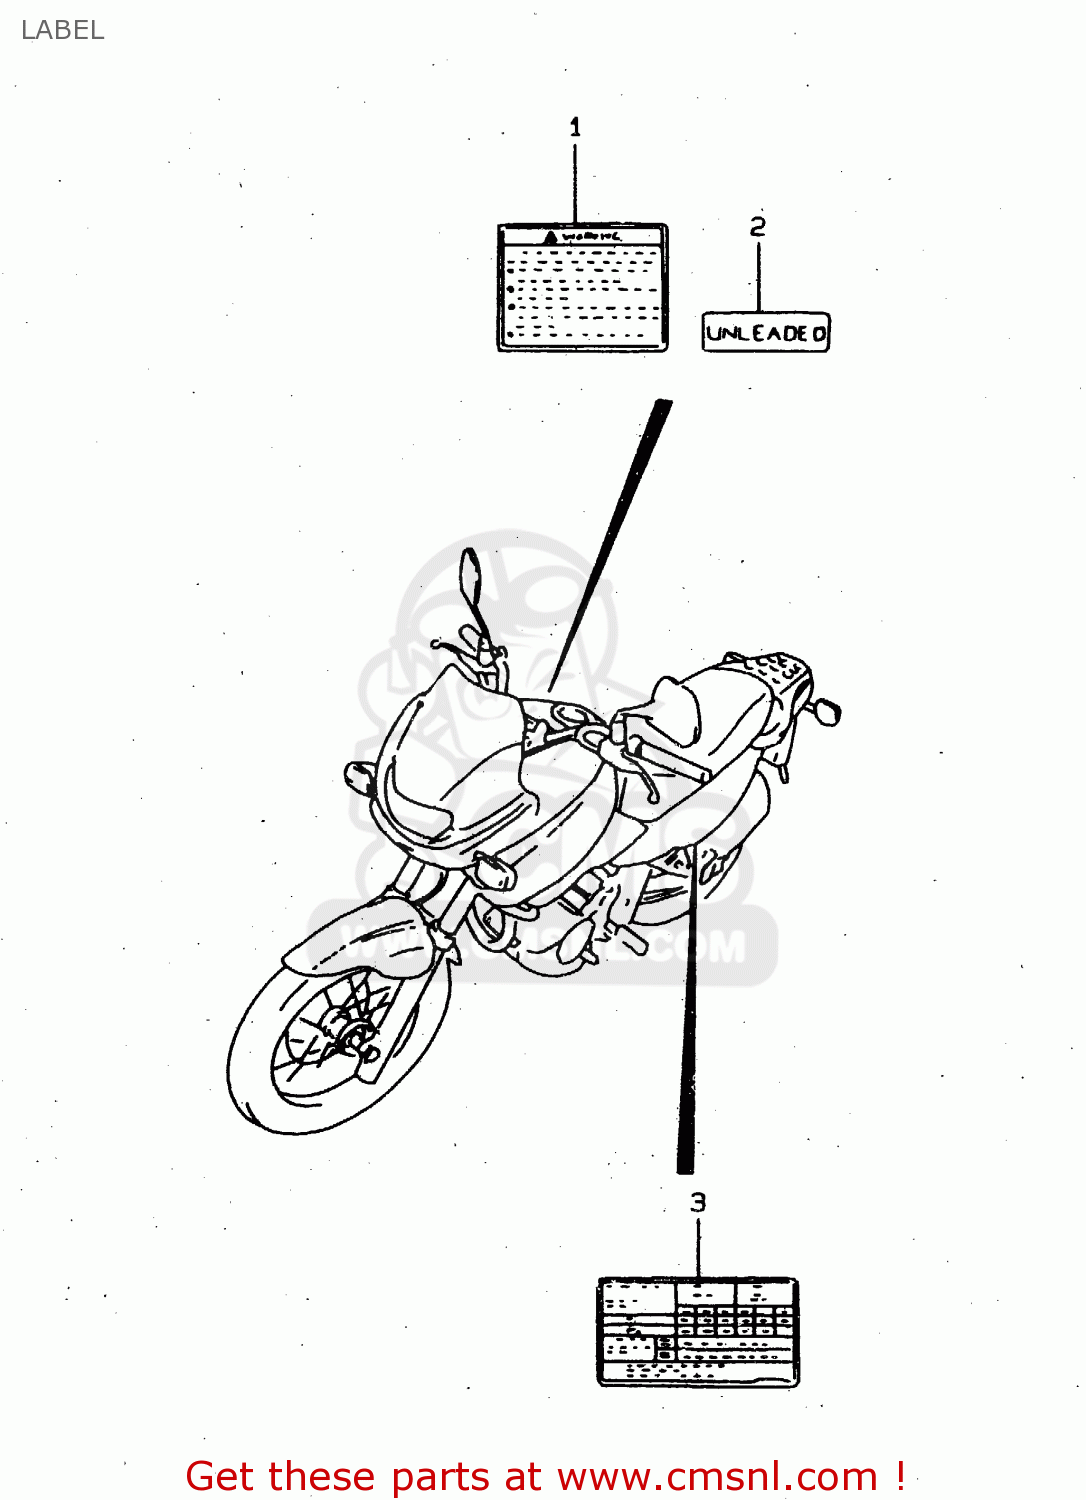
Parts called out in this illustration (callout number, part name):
1	LABEL,WARNING
2	LABEL,CAUTION
3	LABEL, TIRE INFORMATION
4	O.M. XF650 V
